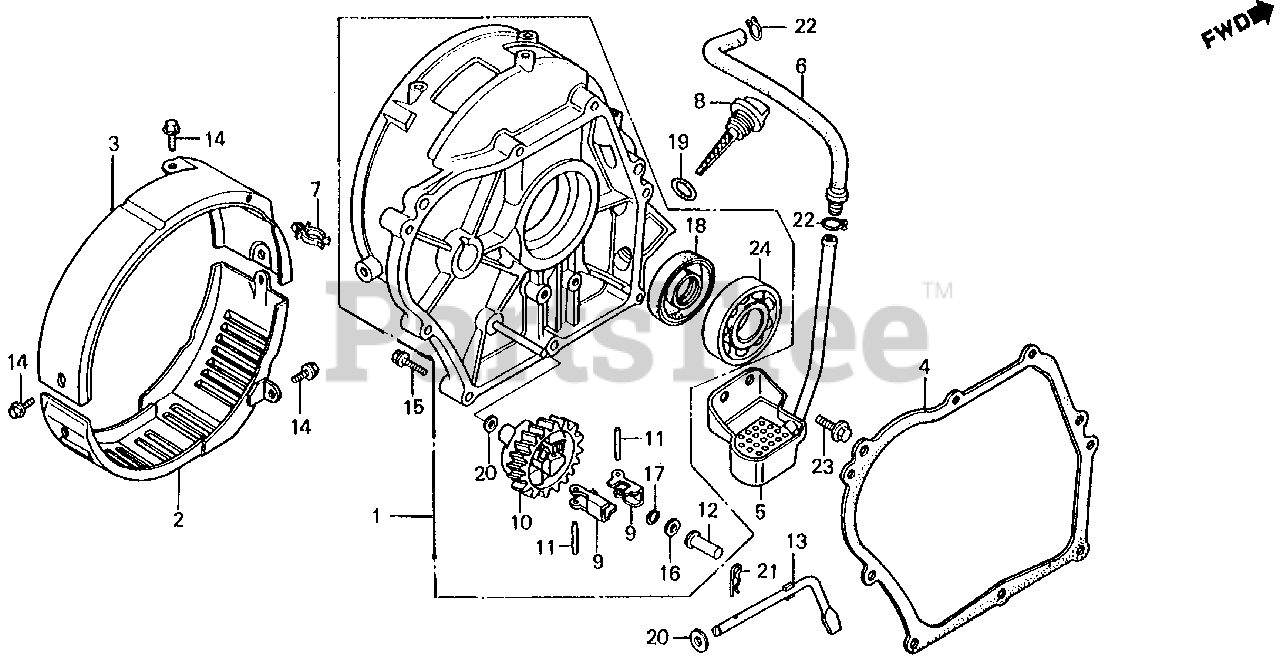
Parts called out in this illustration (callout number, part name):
1	COVER ASSY., CRANKCASE (NOT AVAILABLE)
2	COVER, DUCT (LOWER) (NOT AVAILABLE)
3	COVER, DUCT (UPPER)
4	GASKET, COVER
6	TUBE, OIL ALERT
7	CLIP, TUBE
8	CAP, OIL FILLER
9	WEIGHT, GOVERNOR
10	HOLDER, GOVERNOR WEIGHT
11	PIN, GOVERNOR WEIGHT
12	SLIDER, GOVERNOR
13	SHAFT, GOVERNOR ARM
14	BOLT, FLANGE (6X12) (CT200)
15	BOLT, FLANGE (6X32)
16	WASHER, THRUST (6MM)
17	CLIP, GOVERNOR HOLDER
18	OIL SEAL (25X41.25X6)
19	O-RING (16MM)
20	WASHER, PLAIN (6MM)
21	PIN, LOCK (10MM)
22	CLIP, TUBE (C11)
23	BOLT, FLANGE (6X12)
24	BEARING, RADIAL BALL (6205)
